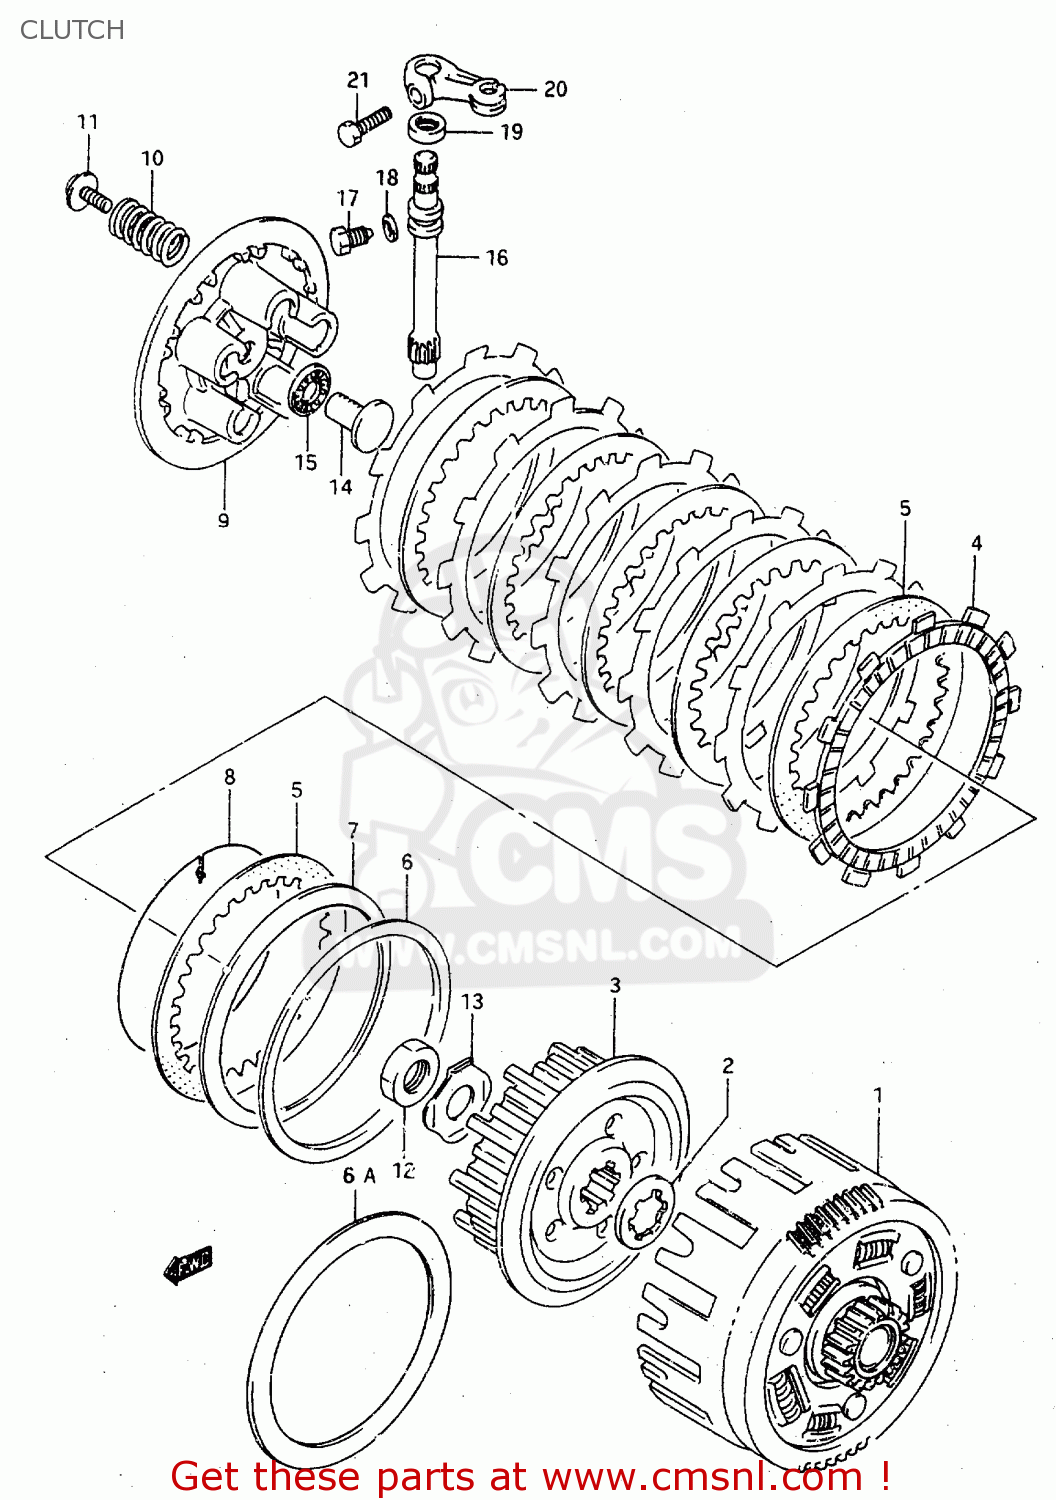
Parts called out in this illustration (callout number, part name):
1	GEAR ASSY,PRI DRIVEN
2	WASHER
3	HUB,CLUTCH SLEEVE
4	PLATE,CLUTCH DRIVE(T:3.0) (NAS)
5	PLATE,CLUTCH DRIVEN(T:2.0) (NAS)
6	SEAT,WAVE WASHER
6A	SEAT,WAVE WASHER
7	WASHER
8	RING,STOPPER
9	DISC,CLUTCH PRESSURE
10	SPRING
11	BOLT 5X16
12	NUT
13	WASHER
14	RACK,CLUTCH RELEASE
15	BEARING(10X22X2.8)
16	PINION,CLUTCH RELEASE
17	BOLT(6X12)
18	WASHER
19	SEAL,OIL(10X17X5)
20	ARM,CLUTCH RELEASE
21	BOLT
